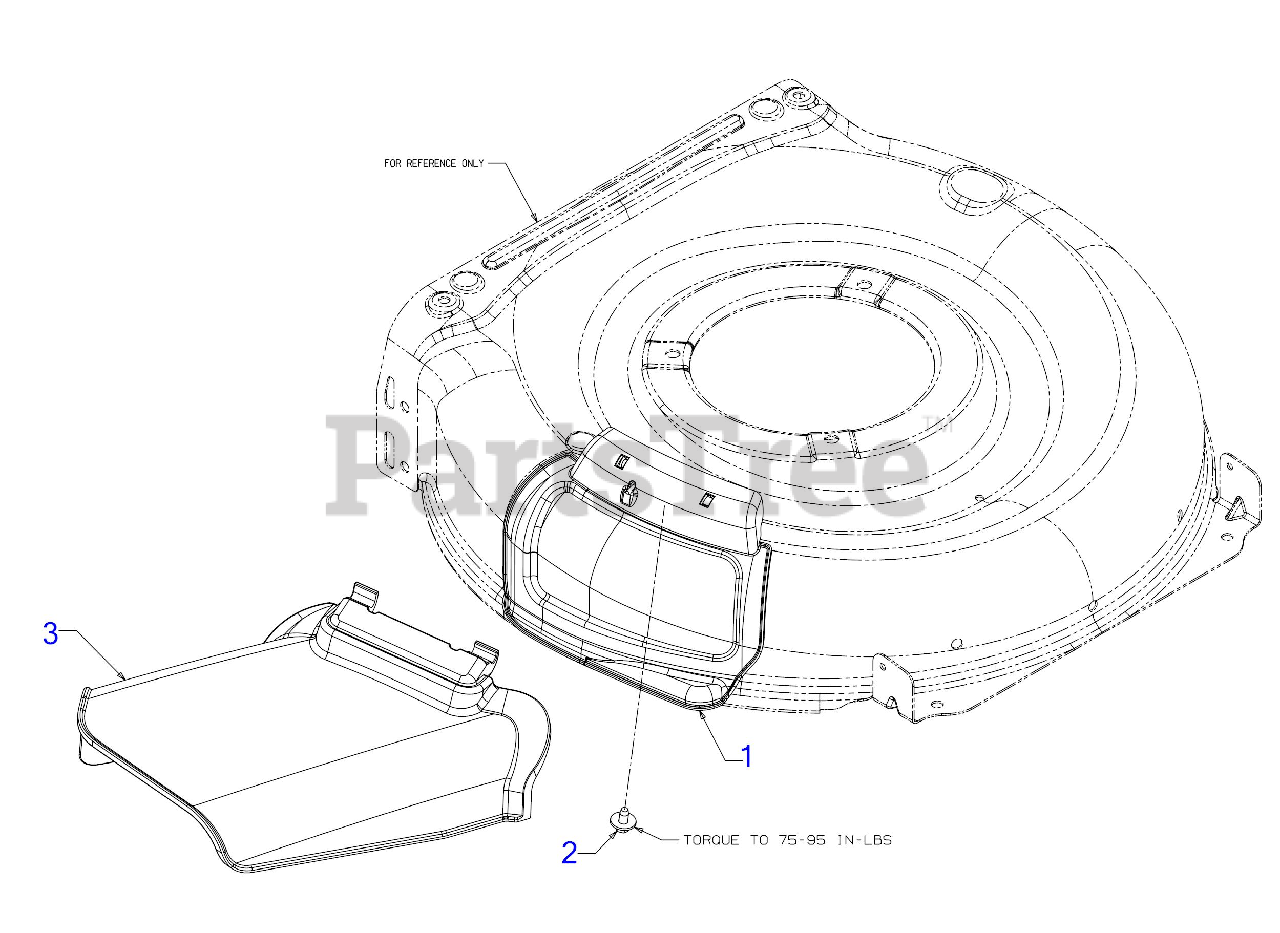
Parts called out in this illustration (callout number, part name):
1	MULCH PLUG ASSEMBLY
2	SCREW 1/4-20 x .50
3	SIDE DISCHARGE CHUTE
